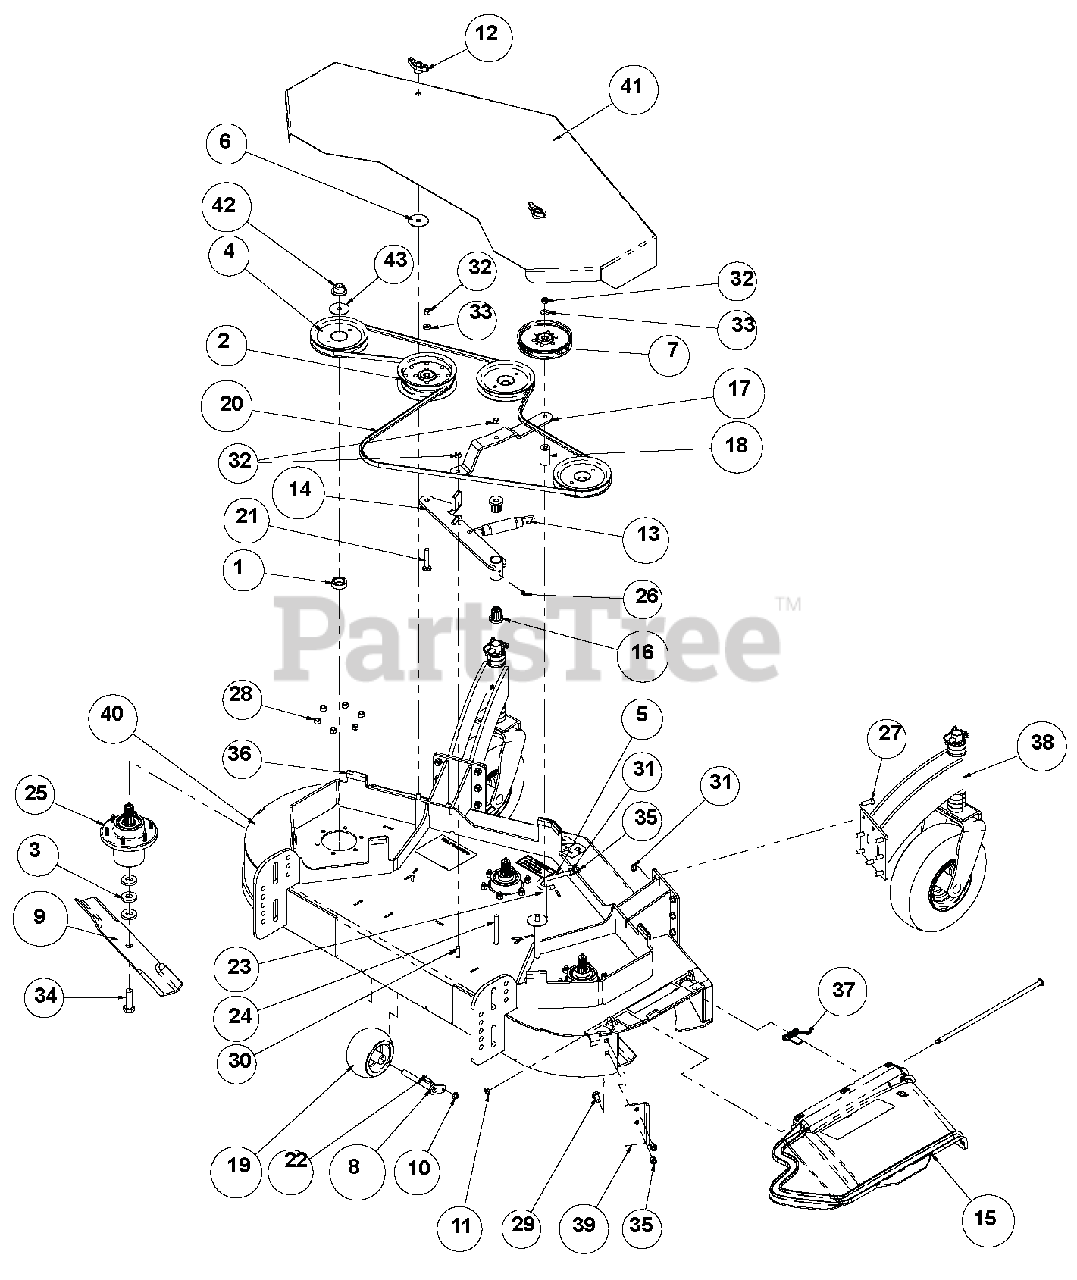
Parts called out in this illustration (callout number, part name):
1	SPACER, PULLEY
2	PULLEY, FLAT TENSION IDLER
3	SPACER, BLADE BOLT
4	PULLEY, SPLINE SPINDLE LSE
5	J-HOOK
6	WSHR-FL-STL .402X2.00X.055 YWZ
7	PULLEY, FLAT BLADE-TO-BLADE
8	PIVOT, ANTI-SCALP ROLLER
9	18.0" BLADE, 52" DECK
10	NUT-1/4" FLANGE PREVAILING TOR
11	CLIP, RETAINER
12	KNOB, 3/8-16 INSERT
13	SPRING, DECK BELT TENSION
14	ARM, IDLER ENGINE-TO-BLADE
15	DISCHARGE CHUTE, 48" DECK
16	BRG, FLG M10XM25XM27 FLUTED
17	STRAP, IDLER PULLEY
18	SPACER, BLADE-TO-BLADE PULLEY
19	V-BELT, 4L-RAW EDGE
20	BELT, ENGINE-TO-BLADES, 52"DEC
21	@BLT-RDHDSQNK .38-16X2.25 G5YZ
22	BOLT, 1/4 X 1.00 A17D ZINC
23	BOLT, 3/8-16 X 3-3/4 CHCS
24	BOLT, 3/8-16 X 4.00 CHCS
25	ASSY, SPINDLE S/O
26	GREASE ZERK, 1/4-28 STR .69 LG
27	@BLT-HEX .38-16X1.00 GR5 YWZC
28	@NUT-HEX .31-18 YWZC
29	@BLT-RDHDSHSQNK.38-16X1.0 G5YZ
30	@BLT-RDHDSQNK .38-16X1.25 G5YZ
31	@NUT-SPNLK-FLG .375-16 YWZC
32	NUT, .38-16 LOW CROWN LK ACORN
33	@WSHR-FL-STL.406X.812X.065 YWZ
34	BOLT, 5/8-11 X 2.00 HEX 8 Y
35	@NUT-LK-NYL .38-16 YWZC
36	TRIM, LOCK 1/4" EDGE
37	SPRING, TORSION .460"X.138"
38	ASSY, WHEEL & STRUT (ARIENS)
39	PLATE, EXTENDER 48" HYDRO
40	ASSY, 52 ARIENS FIXED DECK
41	WLDT, ARIENS DECK SHIELD
42	LOCKNUT, 3/4-16 CROWN PL
43	WASHER, .75X1.3125X.120
